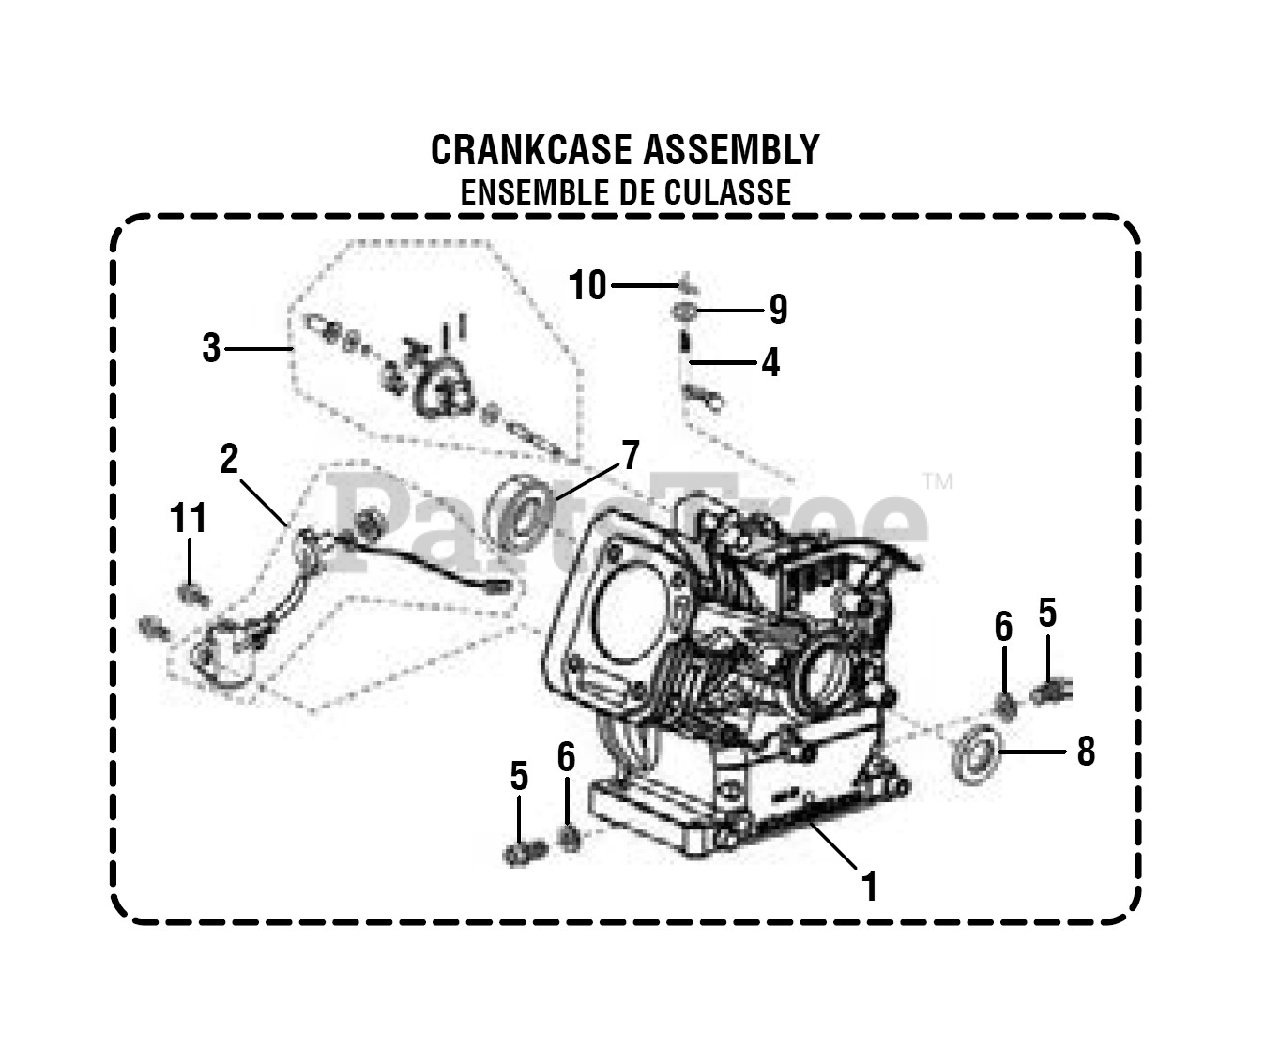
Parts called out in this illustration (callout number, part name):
1	Crankcase Assembly
2	Engine Oil Sensor
3	Governor Gear Assembly
4	Governor Arm
5	Drain Plug
6	Washer
7	Ball Bearing
8	Oil Seal
9	Washer
10	Pin
